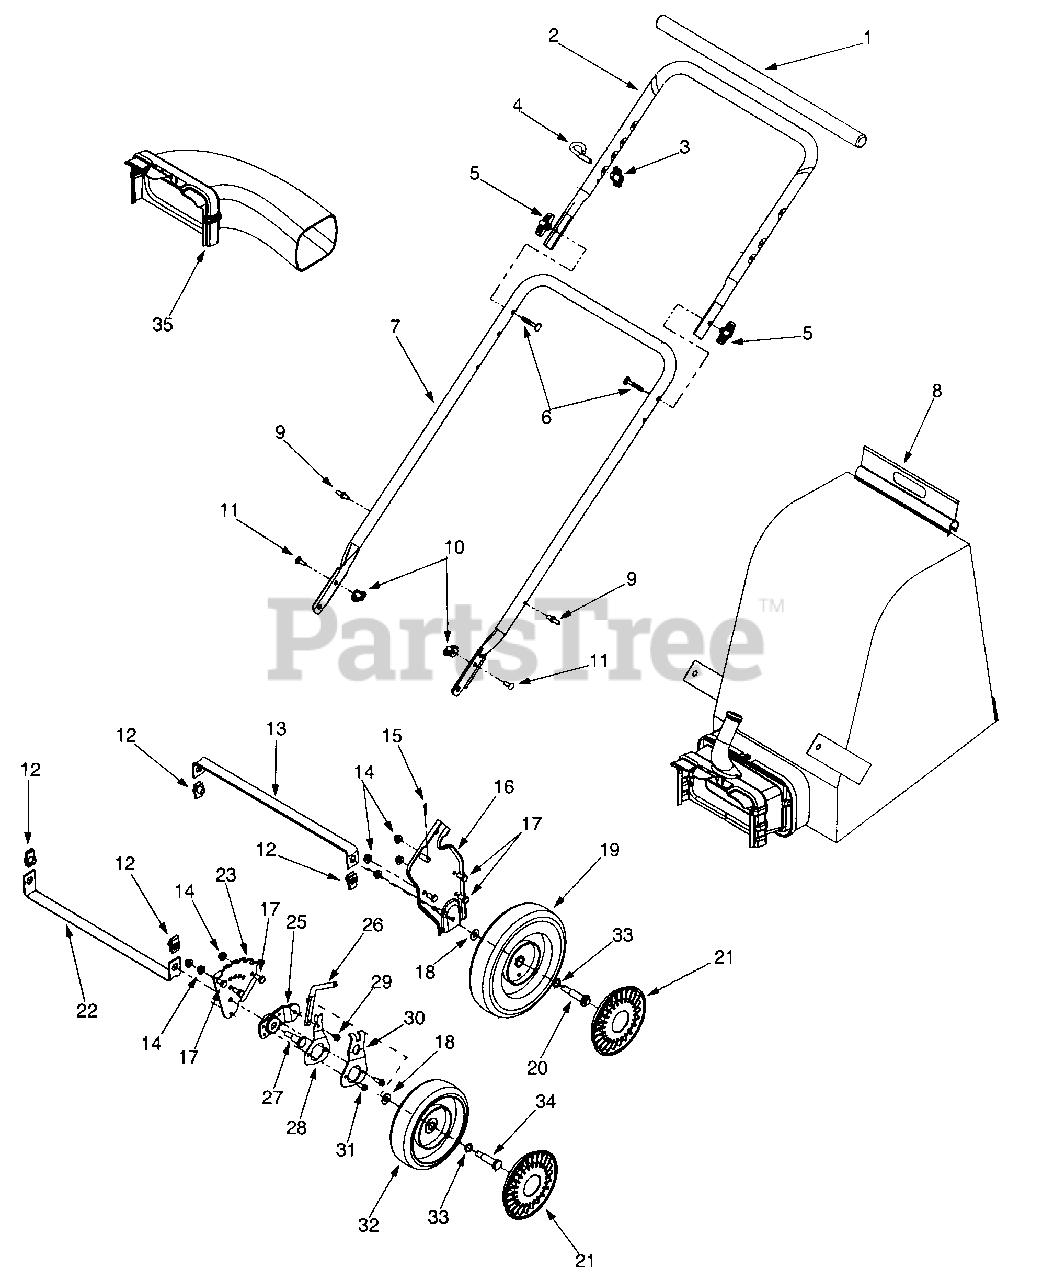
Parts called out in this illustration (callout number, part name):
1	Foam Grip
2	Upper Handle
4	Eye Bolt
5	Handle Knob 5/16-18
6	Carriage Bolt
8	Bag Only
9	Studs
10	Wing Nut 1/4-20
11	Carriage Screw 1/4-20 x .75
12	Lock U-Clip Nut 3/8-16
15	Cotter Pin
17	Hex Cap Screw 5/16-18 x .625
18	Bell Washer .401 ID x .870 OD
19	Wheel 9 x 2
20	Shoulder Screw 3/8-16
21	Hubcap
22	Front Wheel Support Brace
23	Hgt Bracket Adjuster LH
23	Height Brkt Adj RH
25	Pivot Arm
26	Handle Height Adjuster
27	Shoulder Screw 3/8-16
28	Height Adjuster Plate Spring
29	Hex Washer Screw 1/4-20 x .375
32	Wheel 8 x 2
33	Wave Washer .531 ID x .781 OD
34	Shoulder Screw
35	Blower Chute Ass'y
